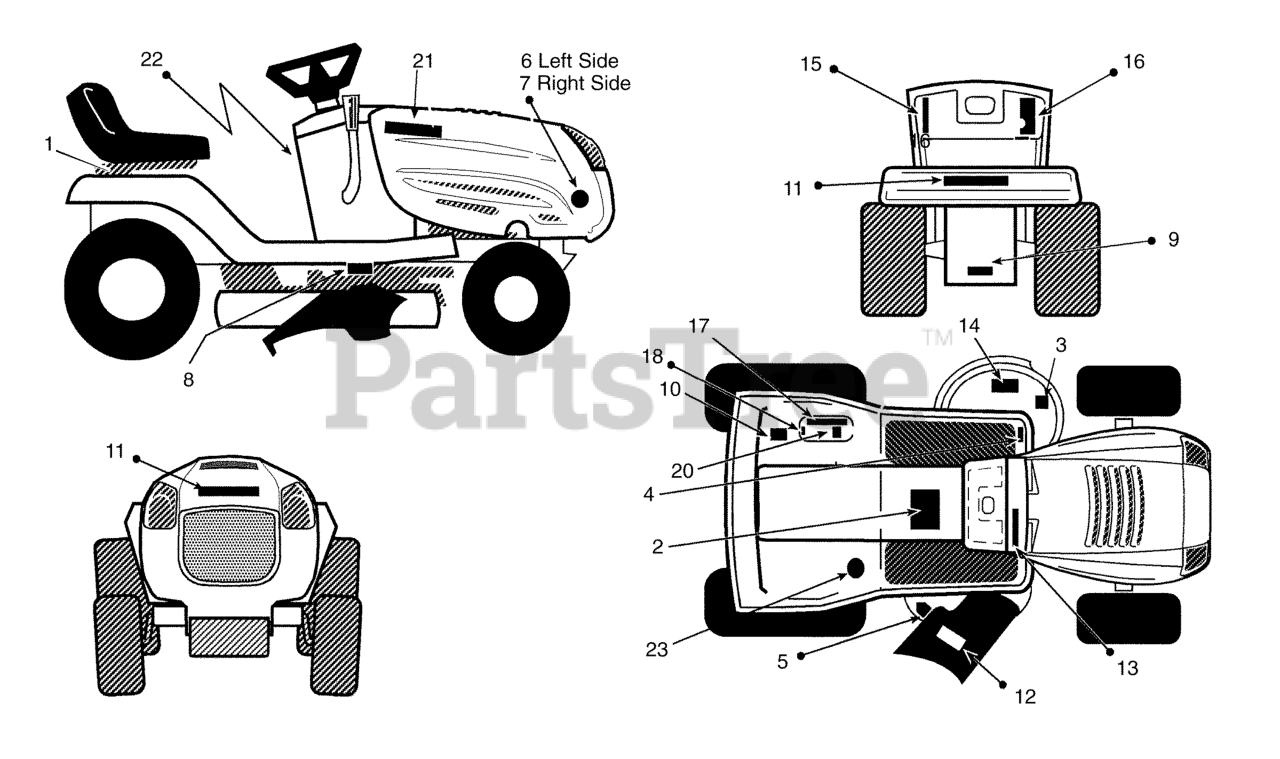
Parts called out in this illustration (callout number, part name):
1	DEKA (Battery)
2	Warning (Console - Center)
3	NO STEP (Mower Deck - Left Side)
4	Park / Brake
5	Cut Finger (Mower Deck -Right Side)
6	20/42 Auto Twin
7	20/42 Auto Twin
8	Gage Wheel Level
9	Warning Load Limit (Rear)
10	Auto Disconnect
11	Craftsman Logo
12	Mulch Kit Installed
13	Hydro Drive
15	Throttle, Twin
16	Ignition & Parking Brake
17	Lifter and Height Adjust
18	Cutting Height
20	Deck Level
21	Craftsman Nameplate
22	Fuel Gauge
23	All Wheel Steer
